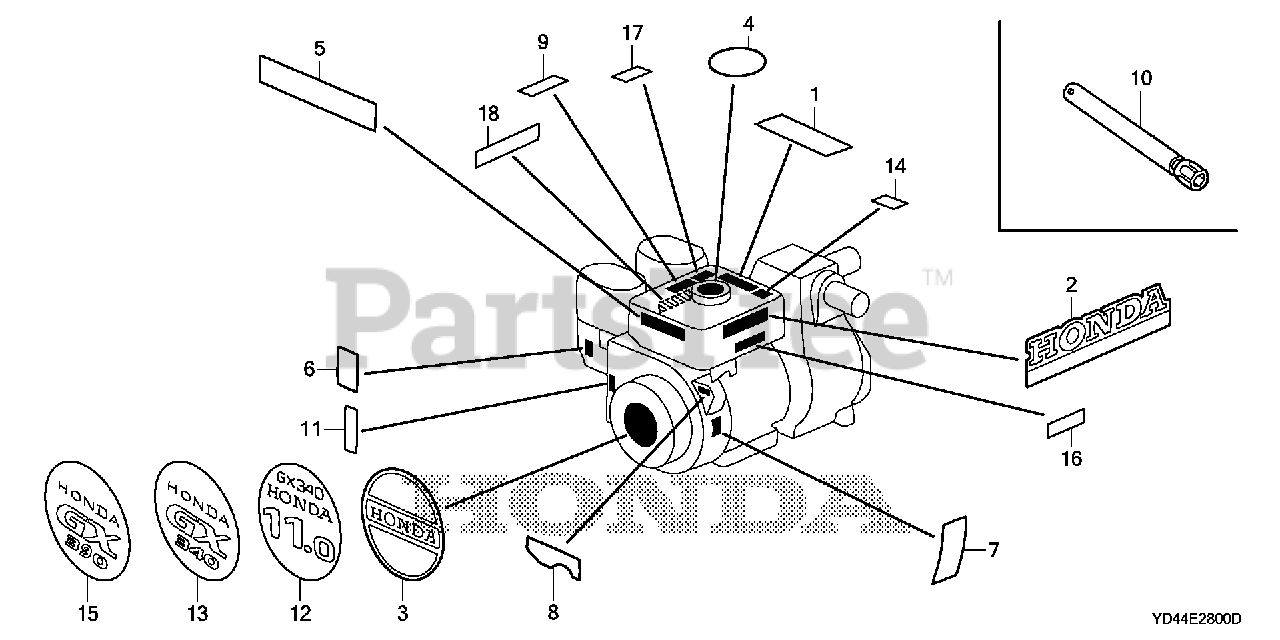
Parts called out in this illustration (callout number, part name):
6	MARK, CHOKE
10	WRENCH, SPARK PLUG
14	LABEL, OPERATOR WARNING (ENGLISH)
15	EMBLEM (GX39 (HONDA)
16	MARK, OIL ALERT (ENGLISH)
17	MARK, EX. CAUTION (ENGLISH)
18	LABEL, SPARK WARNING
